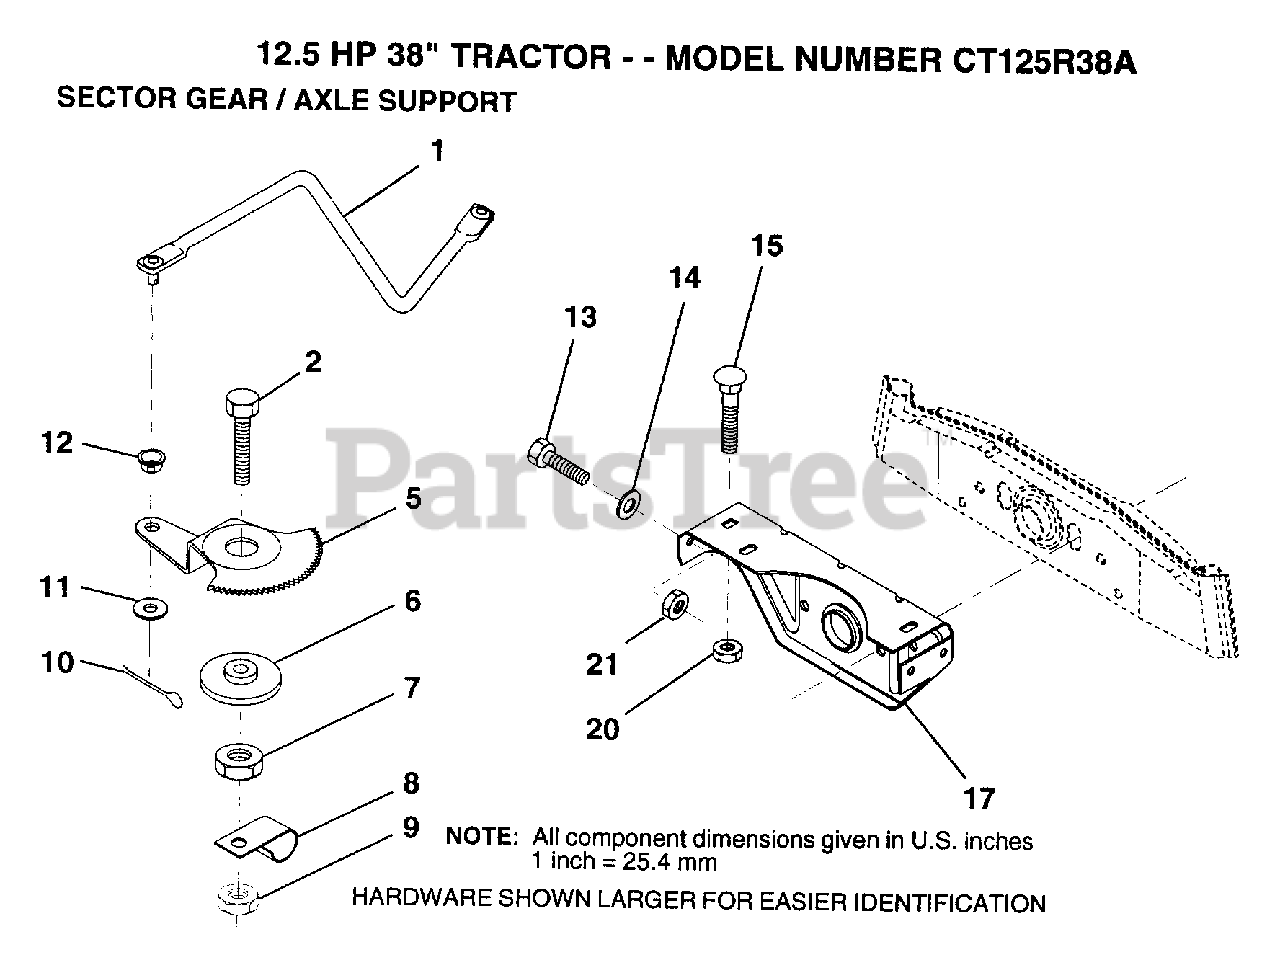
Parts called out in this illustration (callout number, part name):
1	DRAG LINK
2	"BOLT,HEX"
5	GEAR SECTOR
6	BUSHING
7	NUT
8	CLIP INSULATOR
10	COTTER PIN
11	WASHER
12	BUSHING.DRAGLINK
13	BOLT
14	WASHER
15	BOLT
17	SUPT AXLE FRONT
